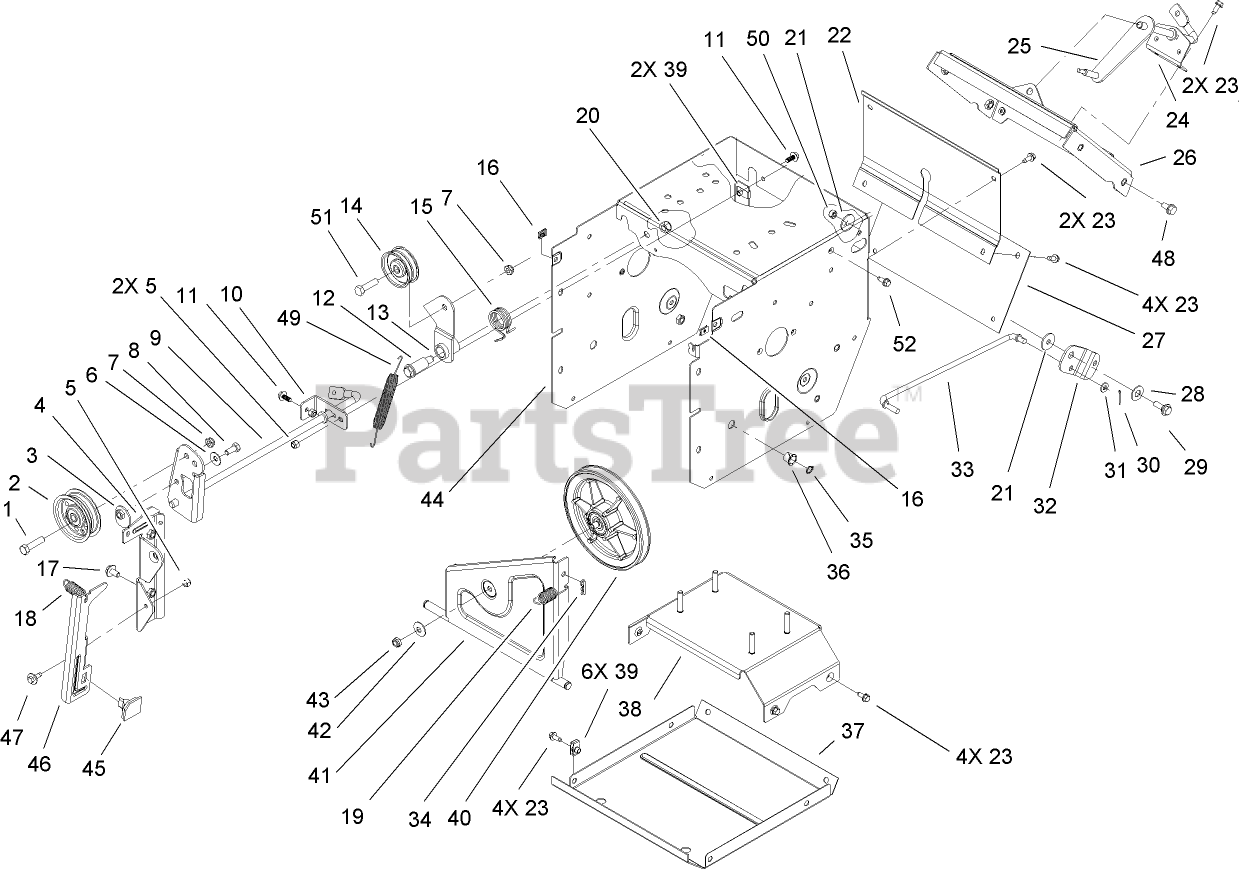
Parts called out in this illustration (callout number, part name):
1	SCREW-HH
2	PULLEY-IDLER
5	NUT-LOCK, NI
6	WASHER-BELLEVILLE
8	SCREW-HH
9	IMPELLER CLUTCH ASM
10	BRACKET-REAR, CLUTCH
11	SCREW-HHF
12	BOLT-SHOULDER
13	ARM-IDLER, TRACTION
14	PULLEY-IDLER
15	SPRING-TORSION
16	NUT-SPEED
17	SCREW-HHF
18	SPRING-EXTENSION
19	SPRING-EXTENSION
20	NUT-LOCK, NI
21	WASHER-PIVOT
22	COVER-UPPER
23	SCREW-HWH
24	BRACKET-ROD, SHIFT
25	LEVER-CONTROL, TRACTION
26	SHIFT PLATE ASM
27	COVER-LOWER
28	WASHER
29	SCREW-SHOULDER
30	PIN-COTTER
31	WASHER-PLAIN
32	BELLCRANK-DRIVE
33	LINK-CONTROL, SPEED
35	RING-RETAINING
36	BUSHING-NYLINER
37	PAN-BOTTOM
38	FRAME BRACE ASM
40	PULLEY-TRACTION
41	BRACKET-WHEEL, FRICTION
42	WASHER-BELLEVILLE
43	NUT-HEX
44	TRACTION FRAME ASM
45	PAD-BRAKE
47	SCREW-SHOULDER
48	SCREW-HWHTF
50	NUT-LOCK, NI
51	SCREW-HH
52	SCREW-HWH
